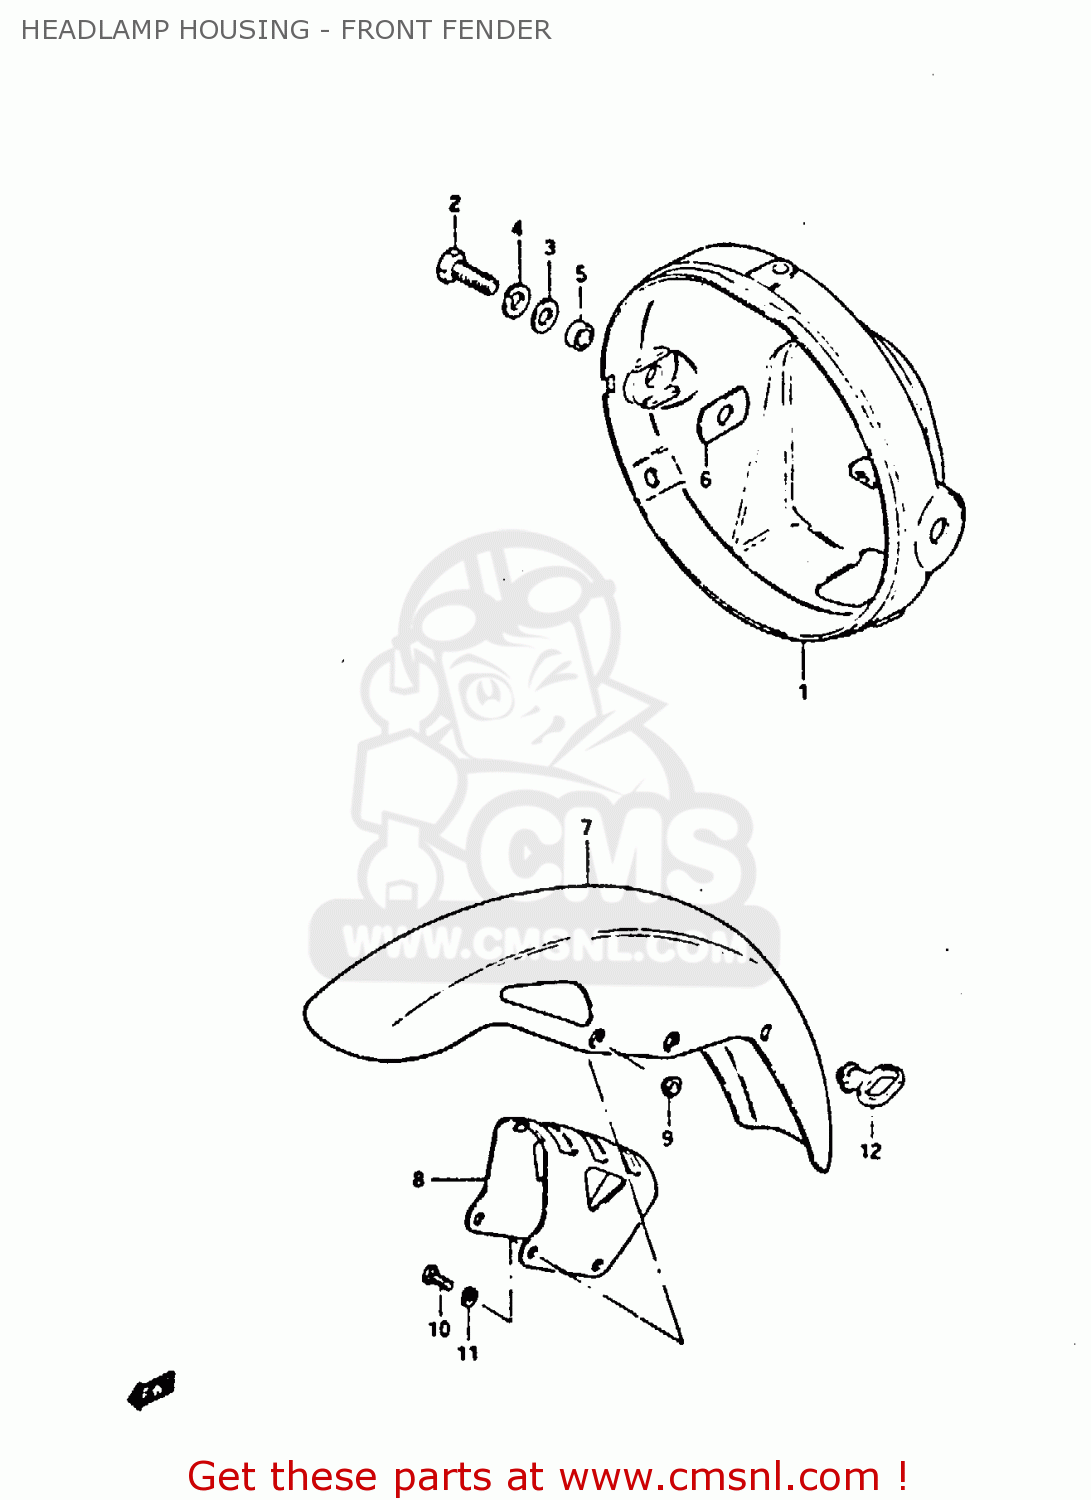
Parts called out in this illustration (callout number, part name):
1	HOUSING,HEADLAMP
2	BOLT
3	WASHER
4	LOCK WASHER
5	SPACER (8.8X12X7)
6	CUSHION
7	FENDER,FR
8	BRACE,FRONT FENDER
9	WASHER
10	BOLT,8X16
11	LOCK WASHER
12	GUIDE,CABLE
